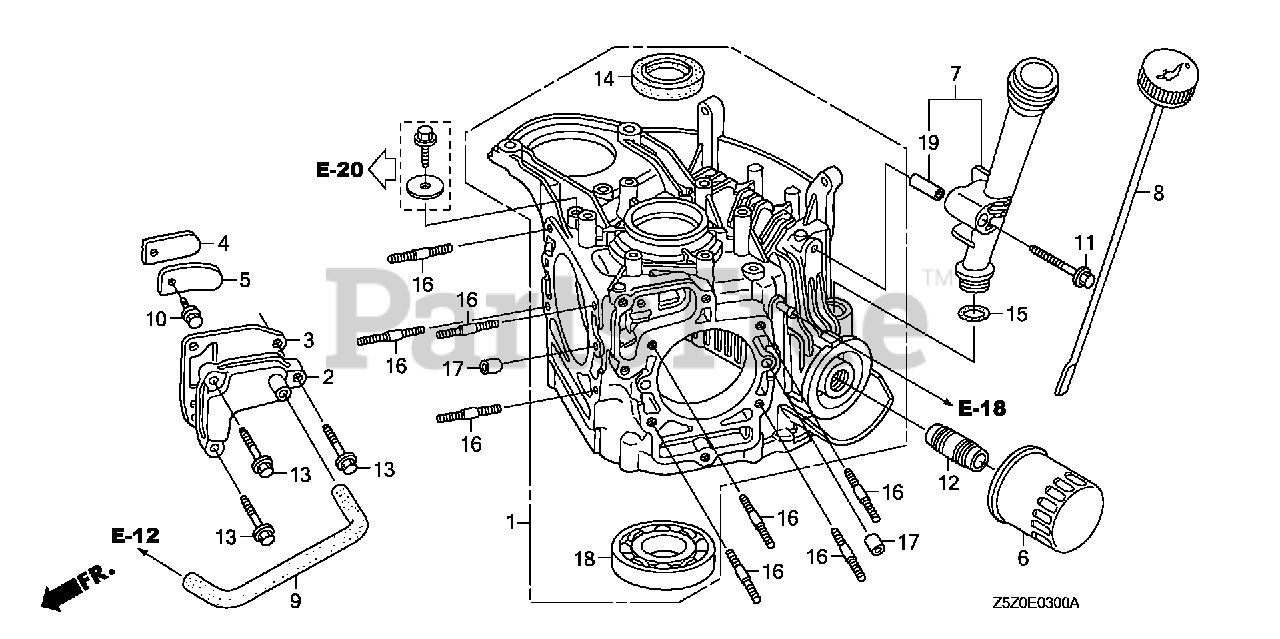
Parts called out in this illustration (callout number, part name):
1	CRANKCASE ASSY.
2	COVER, BREATHER
3	GASKET, BREATHER COVER
4	PLATE, VALVE
5	STOPPER, VALVE
7	EXTENSION, OIL FILLER
8	DIPSTICK, OIL
9	TUBE, BREATHER
10	BOLT, FLANGE (5X10)
11	BOLT, FLANGE (6X45) (CT200)
13	BOLT, FLANGE (6X25) (CT200)
14	OIL SEAL (35X52X8)
15	O-RING (22.1X2.2)
16	BOLT, STUD (8X28)
17	PIN, DOWEL (8X14)
18	BEARING, RADIAL BALL (6207)
19	COLLAR, EXTENSION
